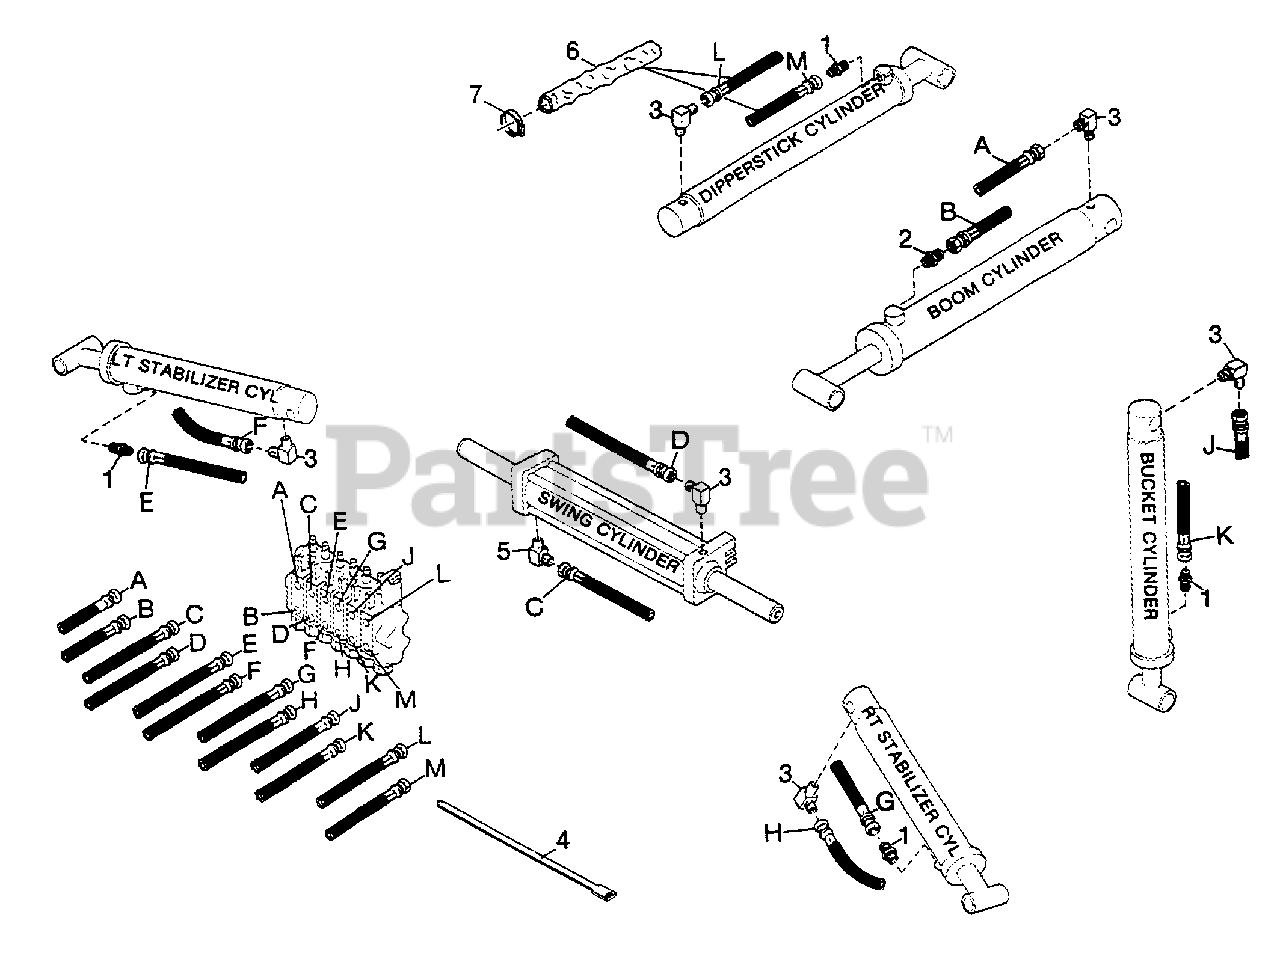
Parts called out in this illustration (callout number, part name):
1	Connector
2	9/16 x 1/4 Male restrictor connector
3	9/16-18 x 1/4 NPTF 90° Fitting
4	Hydraulic hose tie, 7" long
5	9/16 x 1/4 NPT 90° Fitting with 1/16 restriction
6	Hose sleeve 13"
7	1/2 Hose screw clamp
A	Female 9/16-18 flare x 99 high pressure hose assembly
B	Female 9/16-18 flare x 99 high pressure hose assembly
C	Female 9/16-18 flare x 49 high pressure hose assembly
D	Female 9/16-18 flare x 49 high pressure hose assembly
E	Female 9/16-18 flare x 49 high pressure hose assembly
F	Female 9/16-18 flare x 50 high pressure hose assembly
G	Female 9/16-18 flare x 49 high pressure hose assembly
H	Female 9/16-18 flare x 50 high pressure hose assembly
J	Female 9/16-18 flare x 124 high pressure hose assembly
K	Female 9/16-18 flare x 124 high pressure hose assembly
L	Female 9/16-18 flare x 99 high pressure hose assembly
M	Female 9/16-18 flare x 99 high pressure hose assembly
